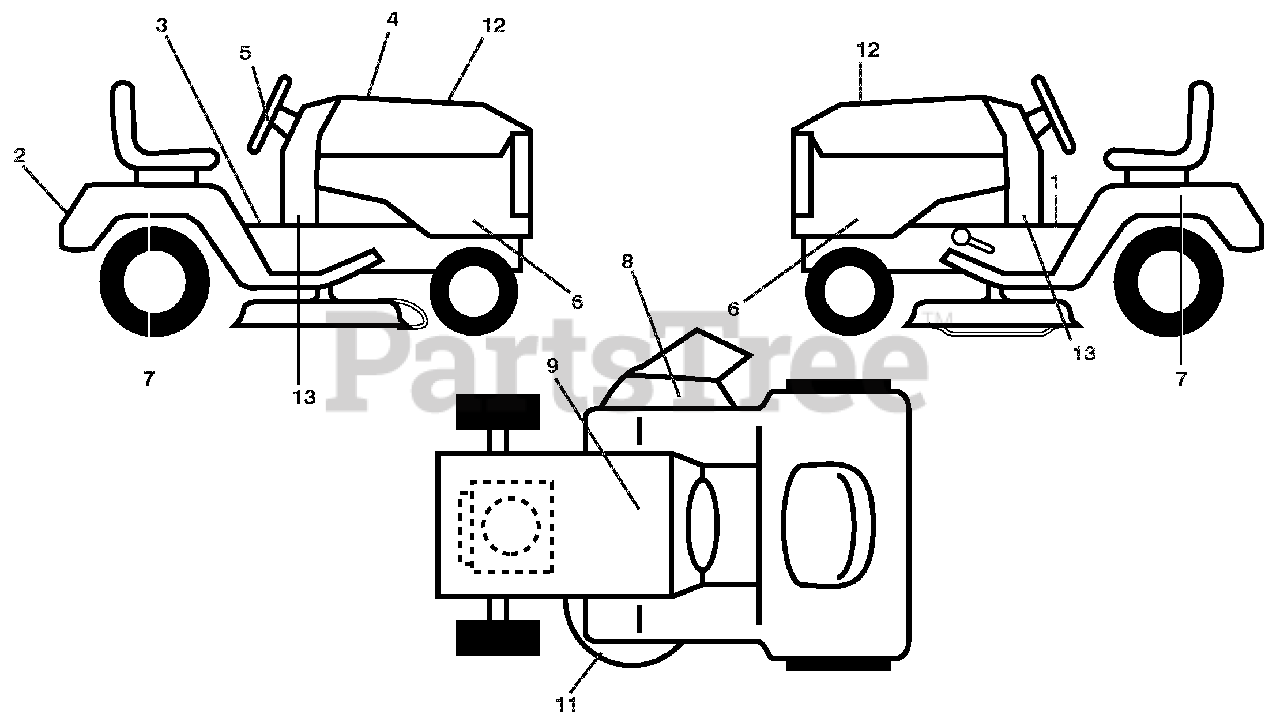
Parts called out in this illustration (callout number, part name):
1	DECAL.WARNING.START
2	DECAL.FENDER.REAR.ARIENS
3	DECAL.FENDER
4	DECAL.RPL.KH(SNGL).TLW.42.PMST
5	DECAL.WHEEL.STEER.ARIENS
6	DECAL.SDPNL.PWRDBY KOHL.ARIENS
7	DECAL, FENDER
8	DECAL DECK/DEFLECT. WARNING
9	DECAL.BAT.DAN/POI P/L SYM.WPN
11	DECAL.V-BELT.SCH.
12	DECAL.HOOD.LH/RH.
13	DECAL, LWDSH
